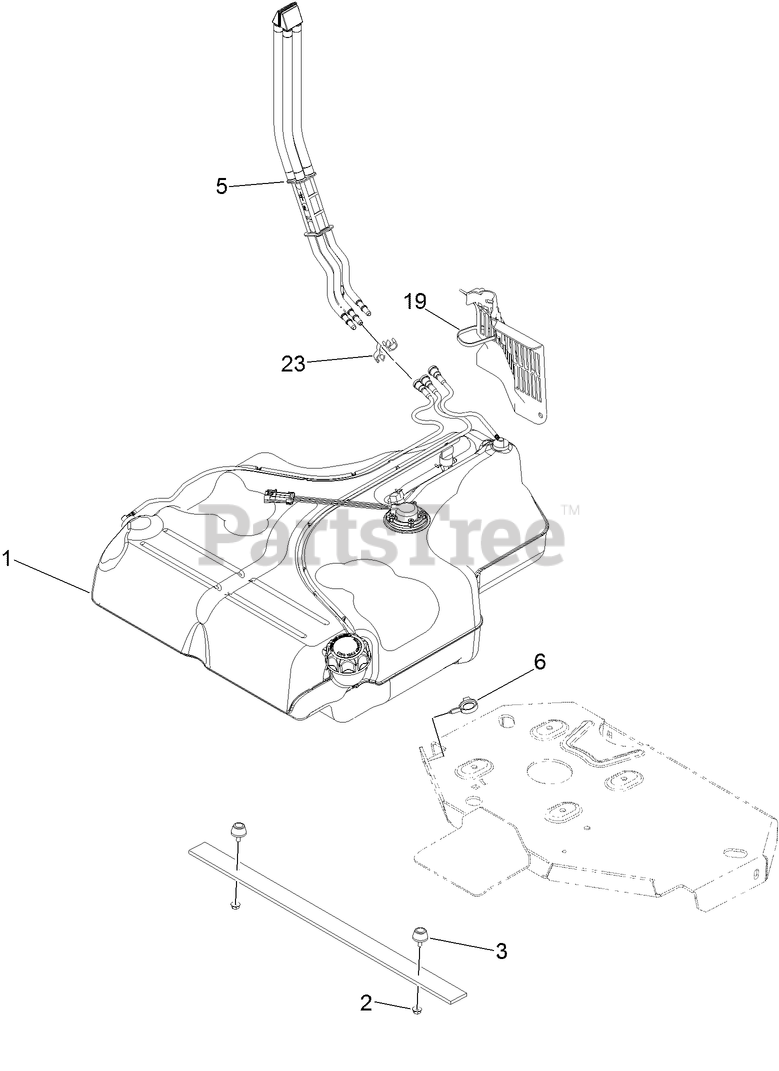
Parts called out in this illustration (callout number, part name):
1	FUEL TANK ASM
2	NUT-HF
3	BUMPER-RUBBER
5	FUEL MANIFOLD VENT ASM
6	CLAMP-HOSE
19	TIE-PLASTIC
23	CLIP-SPACER
